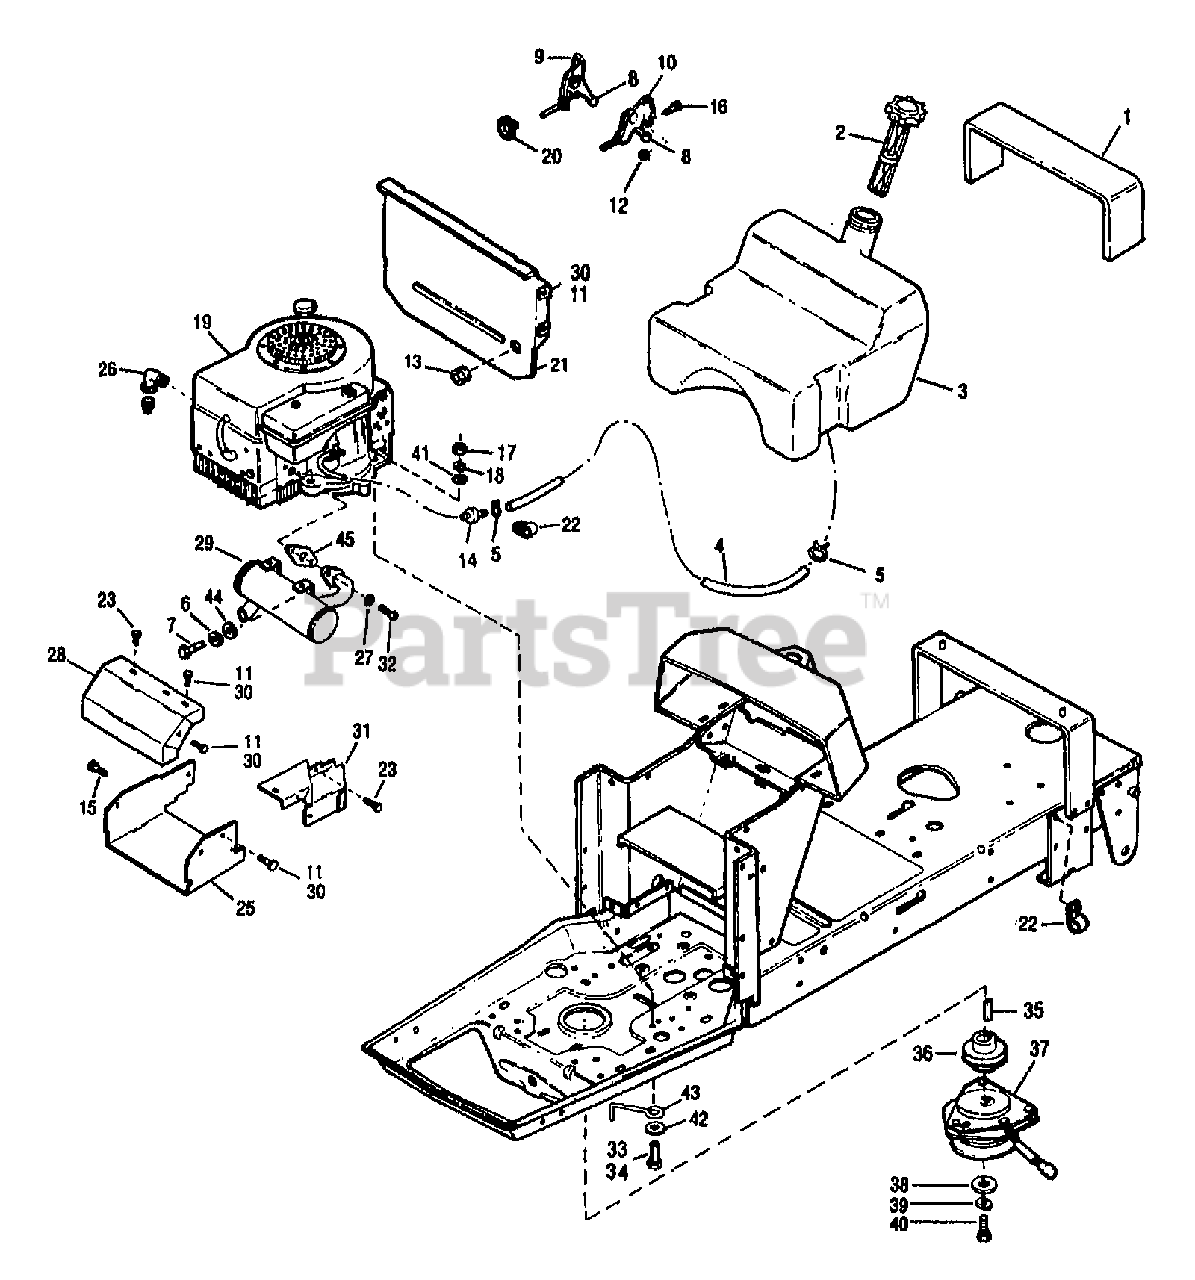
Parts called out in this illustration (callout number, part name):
1	PAD-FUEL TANK
2	CAP-GAS
3	TANK-FUEL
4	LINE-FUEL 52"
5	CLAMP-HOSE
8	KNOB
9	THROTTLE-CONTROL
10	C-CONTROL
13	GROMMET-SPLIT
14	FILTER-FUEL
15	SCR-LOCK
19	ENGINE, BRIGGS & STRATTON 12HP, MODEL 281707
19	ENGINE, BRIGGS & STRATTON 12HP, MODEL 283707
20	TIE-CABLE NYLON BLACK
21	SHIELD-HEAT (RED)
22	CLIP-J
23	SCR-HH 1/4-20X.625
25	SHIELD-HEAT
26	ELBOW-90 DEGREES
27	WASHER-LOCK
28	SHIELD-HEAT
30	NUT-SPEED #10
31	SHIELD-HEAT
32	SCR-HXSKT 5/16-18X.75 BO
35	KEY-.25 SQ X 2.5
36	SHEAVE
37	CLUTCH-ELECTRIC
38	WASHER-SPEC 1.42X.468X.25 ZP
40	SCR-HH 7/16-20X3 G5 ZP
43	CLUTCH-RETAINER
44	SPACER-.625X.344X.34
